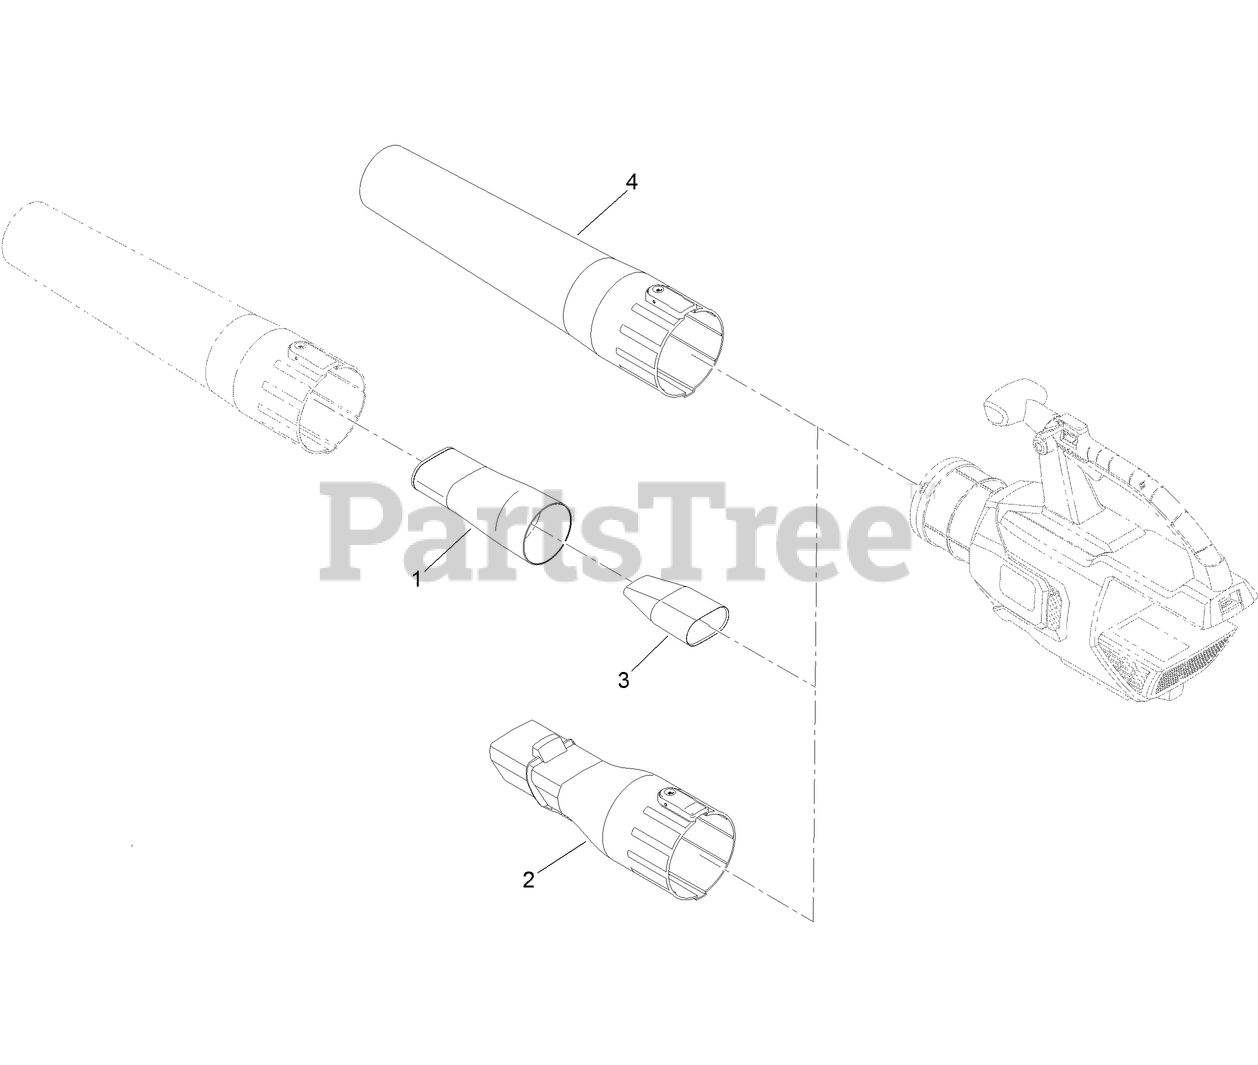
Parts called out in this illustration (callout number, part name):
1	Adapter-Oscillator, MPH
2	ADAPTER-CLEANER, GUTTER
3	Adapter-Insert, MPH
4	TUBE-BLOWER
